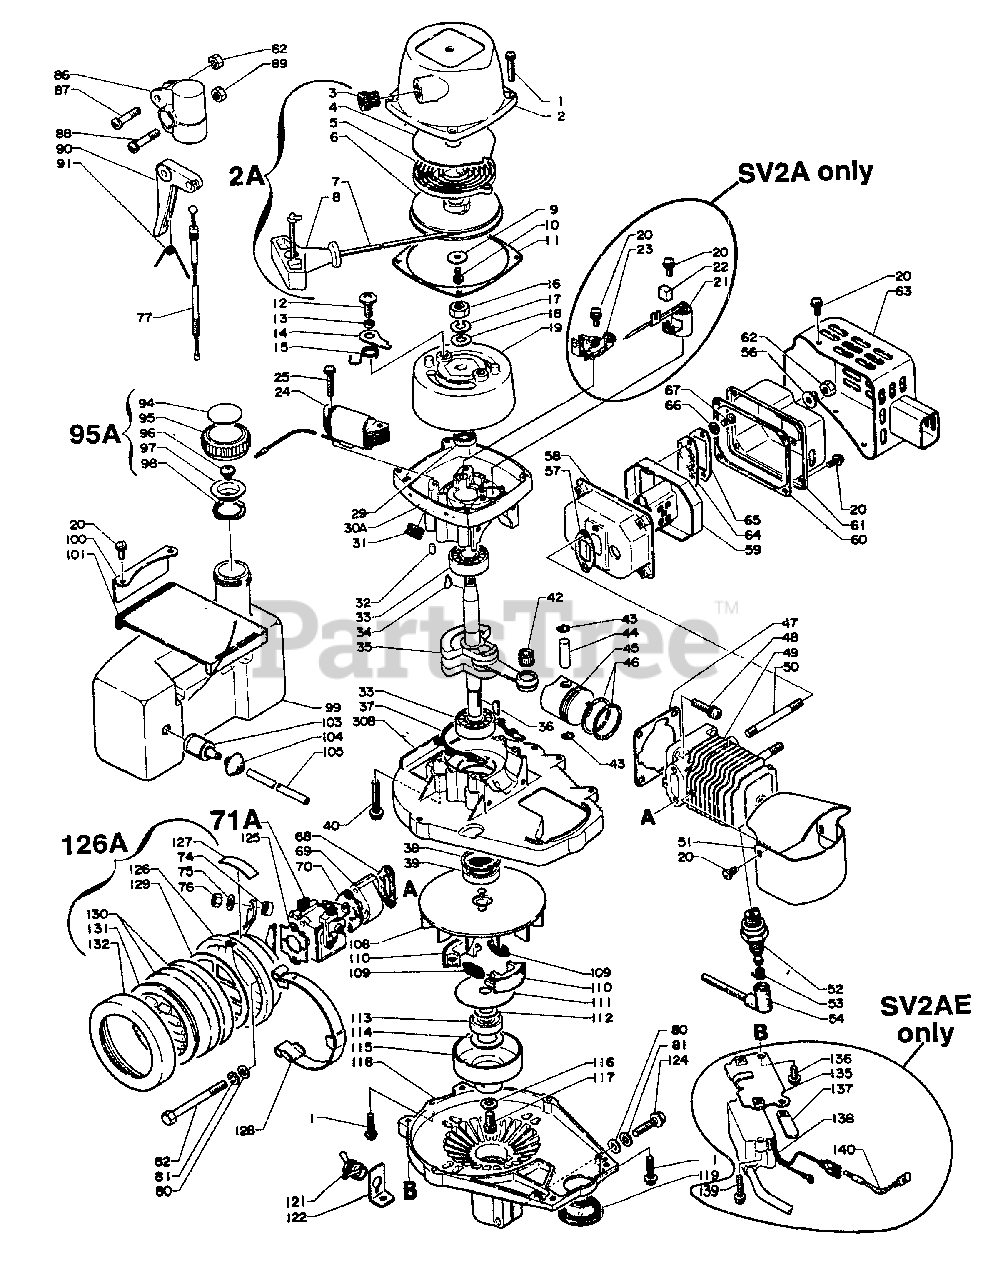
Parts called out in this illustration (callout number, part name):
1	SCREW 4×20
2	CASE, STARTER
2A	STARTER ASSY
3	GUIDE, ROPE
4	PLATE, SIDE
5	SPRING, RECOIL
6	REEL, ROPE
7	ROPE, STARTER 3.5×850
9	WASHER 4.1×15.5×1T
10	SCREW - 4×10
11	GASKET, STARTER
12	SCREW
13	SPACER 5.2×8×2.1
14	PAWL, STARTER
15	SPRING, RETURN
16	NUT 8×1.25
17	WASHER, SPRING 8
19	FLYWHEEL
20	SCREW 4×10
21	CONDENSER
22	PAD, OIL
23	CONTACT POINT SET
24	COIL, IGNITION
24	COIL, EXCITER
25	SCREW 4×25
29	SEAL, OIL
30A	CRANKCASE KIT
30B	CRANKCASE SET
31	GROMMET
31	BUSHING
32	PIN, LOCATING 4
33	BEARING, BALL - 6201 C3
35	CRANKSHAFT
37	GASKET, CRANKCASE
38	RING, SNAP Ø32
39	SEAL, OIL 12
40	SCREW 5×30
42	BEARING, NEEDLE 8
43	RING, SNAP
44	PIN, PISTON
45	PISTON
46	RING, PISTON
47	GASKET, CYLINDER
48	SCREW 5×20
49	CYLINDER
50	STUD
51	COVER, CYLINDER
52	SPARK PLUG - BM6A
53	TERMINAL, SPARK PLUG CAP
54	CAP, SPARK PLUG
56	WASHER 5.5×12×0.8
57	GASKET, EXHAUST
58	MUFFLER
59	SILENCER (S A)
60	GASKET, EXHAUST
61	COVER, MUFFLER
62	LOCKNUT - 5
63	COVER, MUFFLER
64	SCREEN, SPARK ARRESTER
65	RETAINER, SCREEN
66	WASHER, LOCK 4 MM
67	SCREW 4×8
68	GASKET, INTAKE
69	INSULATOR, INTAKE
70	GASKET, INTAKE
71A	CARBURETOR - WA-59
77	CABLE, THROTTLE
80	WASHER, FLAT 5.5×10×0.8
81	WASHER, SPRING 5
86	BRACKET, TRIGGER
88	SCREW 5×25
89	NUT M5
90	TRIGGER, THROTTLE
94	LABEL - FUEL MIX
95	CAP
95A	CAP ASSY
96	VALVE, CHECK
97	HOLDER, VENT
98	GASKET, CAP
99	TANK, FUEL
100	BRACKET, FUEL TANK
101	CUSHION
103	FILTER, FUEL
105	PIPE ASSY
108	FAN
109	SPRING, CLUTCH
110	SHOE, CLUTCH
111	PLATE, CLUTCH
112	WASHER, CLUTCH
113	BEARING, BALL 6000-2RLB
115	DRUM, CLUTCH
116	WASHER 6
117	BOLT M6×10
118	CASE, FAN
119	COVER, SPARK PLUG
120	CLIP
121	SWITCH, ON-OFF
122	BRACKET, SWITCH
124	BOLT - 5×25
125	GASKET, INTAKE
126	CASE, AIR FILTER
126A	AIR FILTER ASSY
127	LABEL - CHOKE
129	RETAINER, AIR FILTER
130	FILTER, AIR
131	COVER, AIR FILTER
132	COVER, AIR FILTER
135	BRACKET, IGNITION COIL
136	SCREW 5×10
137	CLIP
138	COIL, IGNITION
139	SCREW 4×16
140	LEAD - GROUND
